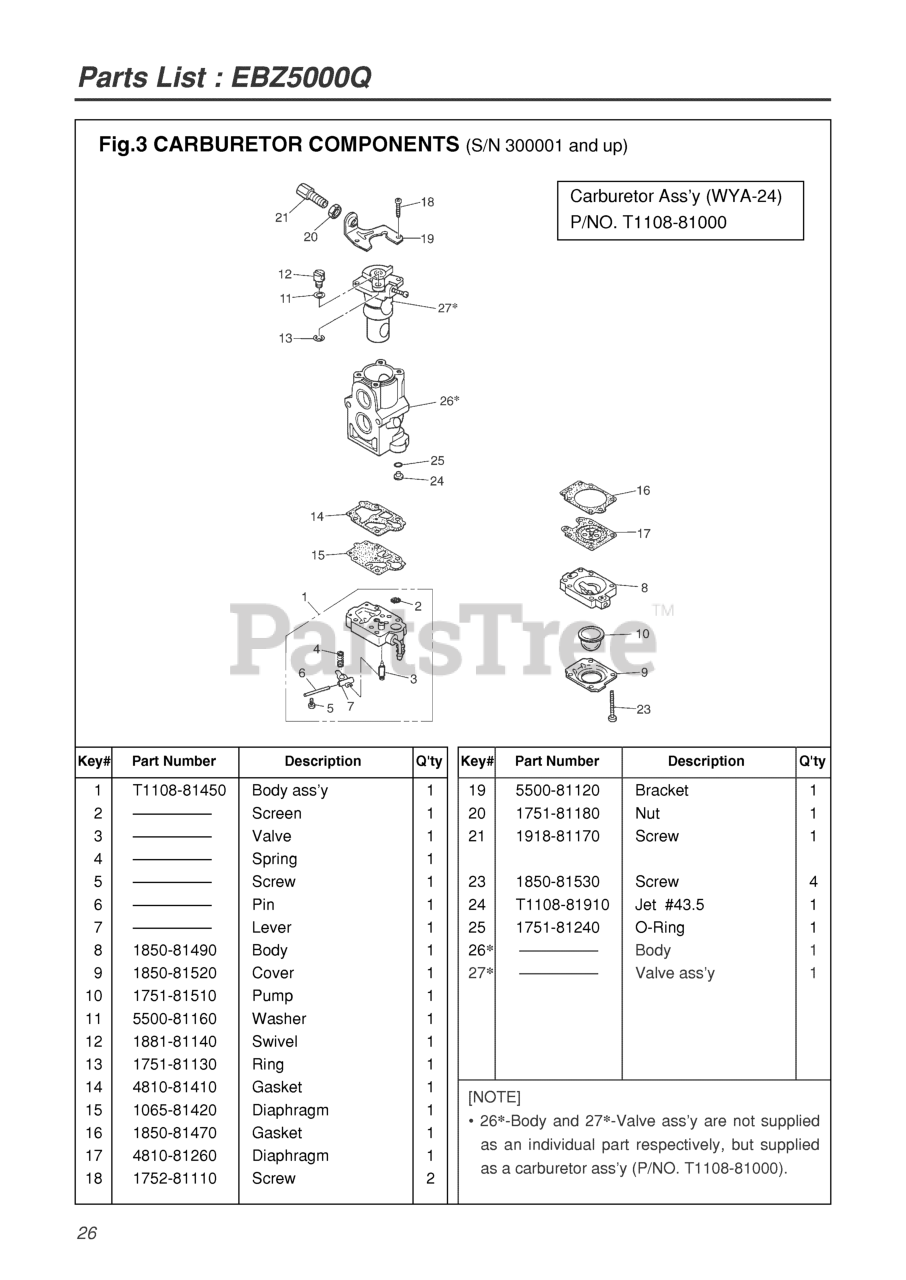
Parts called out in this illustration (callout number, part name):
1	BODY ASSY.
2	SCREEN
3	VALVE
4	SPRING
5	SCREW
6	PIN
7	LEVER
8	BODY, PURGE
9	COVER, PUMP
10	PUMP, PRIMING
11	WASHER
12	SWIVEL
13	RING
14	GASKET, PUMP
15	DIAPHRAGM
16	GASKET, DIAPHRAGM
17	DIAPHRAGM (RPLS 3310-81260)
18	SCREW
20	NUT, CABLE ADJUSTER
21	SCREW, CABLE ADJUSTER
23	SCREW
24	JET 43.5
25	RING, O
26	CARBURETOR (WYA 24A)
27	CARBURETOR (WYA 24A)
NI	CARBURETOR (WYA 24A)
